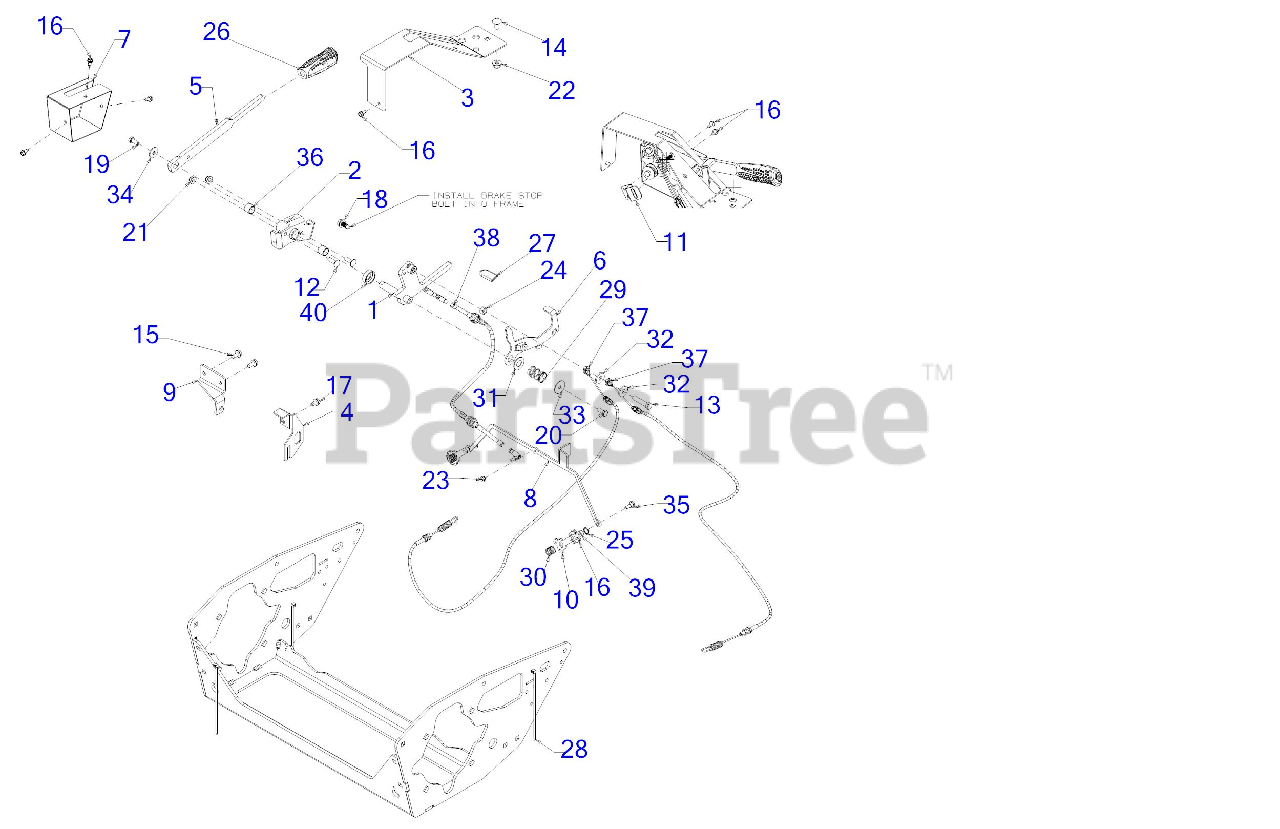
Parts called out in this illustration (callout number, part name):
1	PIVOT BRAKE SHAFT ASSEMBLY
6	DUMP VALVE RELEASE LEVER
8	DUMP VALVE ACTUATOR BRACKET
9	CABLE MOUNTING BRACKET
10	BYPASS LEVER
12	CARRIAGE BOLT 5/16-18 x 1.00
13	HEX SCREW 3/8-16 x 1.75 GR5
14	CARRIAGE BOLT 3/8-16 x .750 GR5
15	SCREW 5/16-18 x .750
16	SCREW 1/4-20 X.500
17	SCREW 5/16-18 x .500
18	HEX SCREW WASH TT 3/8-16 x .875
19	SCREW 5/16-18 x .750
20	SCREW 5/16-18 x .75 GR5
21	FLANGE LOCK NUT 5/16-18
24	HEX NUT
25	SNAP RING
27	SEAT ADJUSTER GRIP
28	7" CABLE TIE
29	COMPRESSION SPRING .844X.970X1.50
30	COMPRESSION SPRING
31	FLAT WASHER .640ID X1.24OD x .06
32	FLAT WASHER .385 x 1.00 x .135
33	FLAT WASHER .322 ID x 1.25 x .060
34	FLAT WASHER 1.0 OD:.331 ID
35	SHOULDER SCREW .375X.280:1/4-14
36	SLEEVE BEARING
37	BRAKE CABLE
38	NEUTRAL CONTROL CABLE
